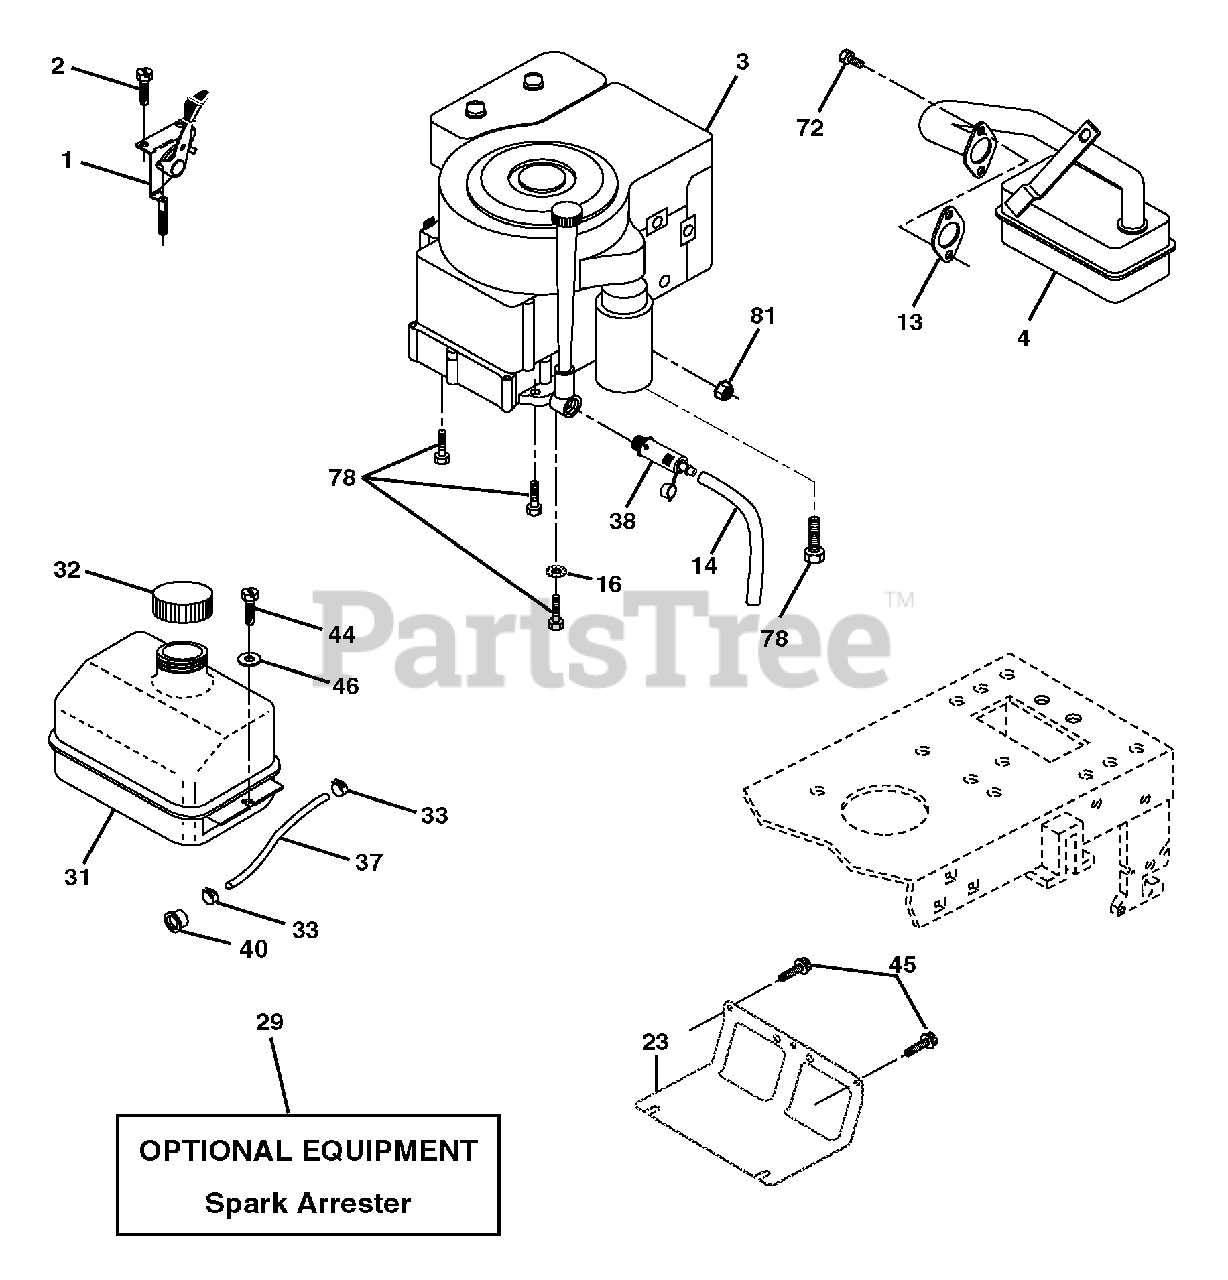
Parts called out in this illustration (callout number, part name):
1	Control, Throttle
2	Screw, Hex Head, Thread Cutting 1/4-20 x 5/8
4	Muffler
13	Gasket
14	Tube Drain Oil Easy
16	Washer
23	Shield Brn/Dbr Guard
29	Arrestor, Spark
31	Tank, Fuel
32	Cap Assembly Fuel
33	Clamp, Hose
37	Line, Fuel
38	Plug, Drain Oil Easy
40	Bushing Snap
44	Screw, Hex Washer Head, Thd., Roll. 1/4-20 x 3/4
45	Screw Hex Wsh Thdr 3/8-16 x 3/4
46	Washer 9/32 x 7/8 x 16 Ga.
62	Washer Lock Hvy HLCL Spr. 5/16
72	Screw Hex Hd Cap 5/16-18 x 3/4
78	Screw 3/8-16 x 1-1/4
81	Nut Keps Hex 1/4-20 Unc
